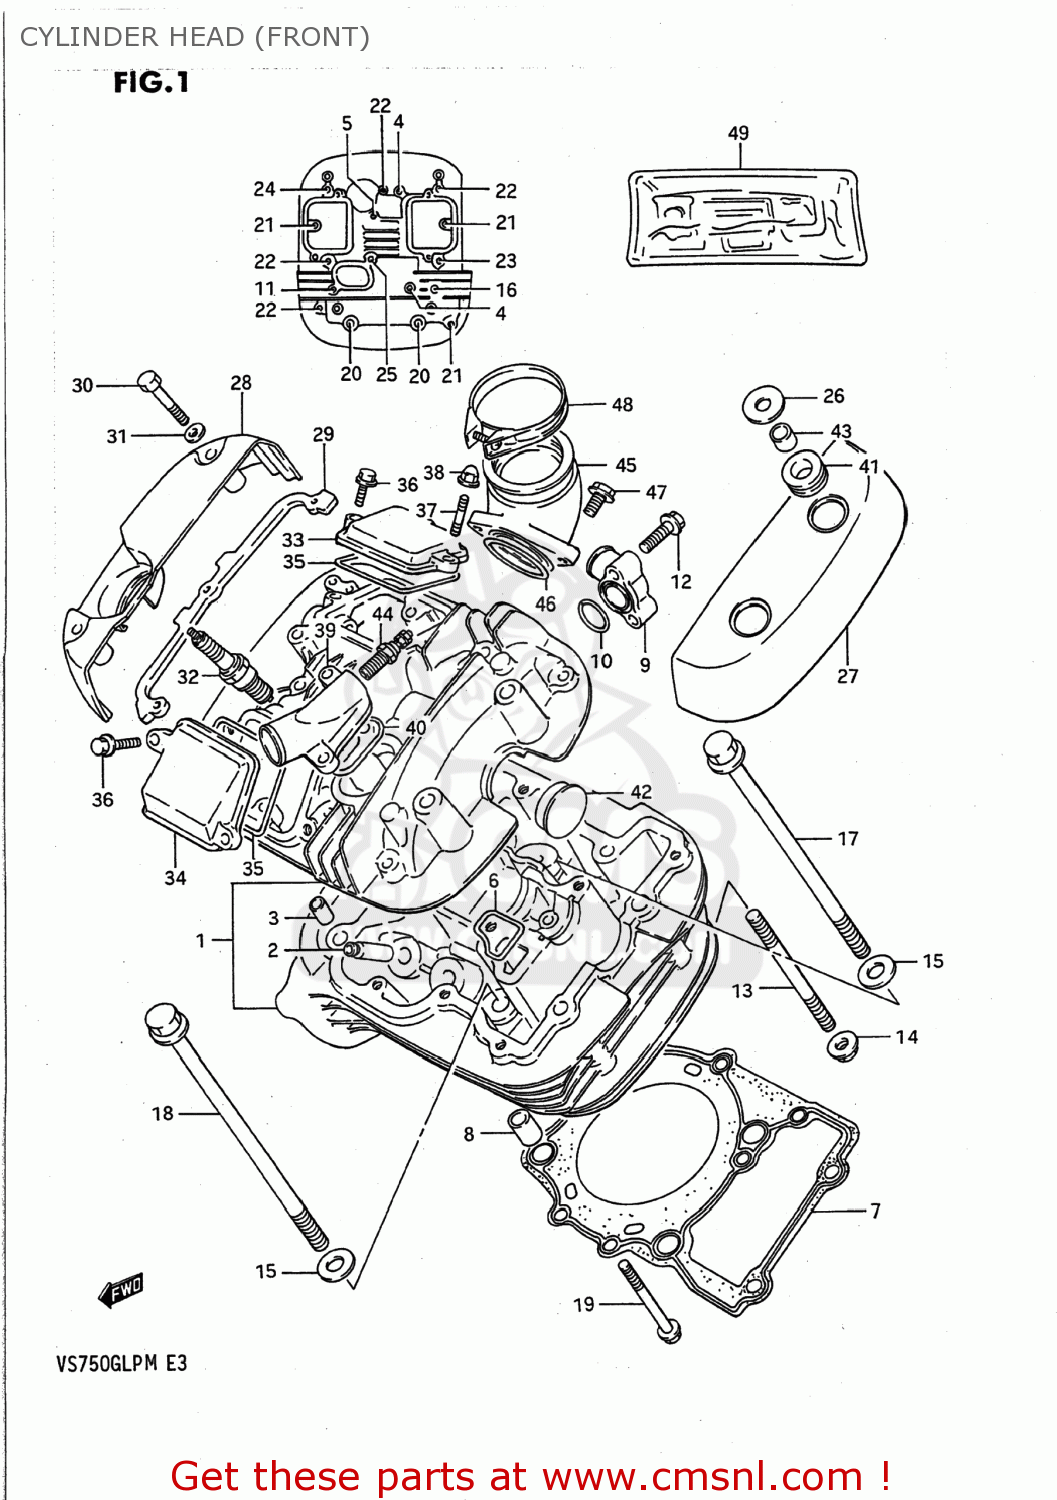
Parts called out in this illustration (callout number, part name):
1	HEAD ASSEMBLY,CYLINDER,FRONT
2	GUIDE,VALVE
3	PIN(11X14)
4	BOLT(6X50)
5	BOLT(6X55)
6	GASKET,CYLINDER HEAD WATER (NAS)
7	GASKET,CYLINDER HEAD FR (MCA)
8	PIN
9	UNION,CYLINDER HEAD WATER
10	O RING(D:2.4,ID:17.8)
11	BOLT 6X20
12	BOLT
13	BOLT,STUD
14	NUT
15	WASHER(10.5X22X2.3)
16	BOLT(8X140)
17	BOLT(10X155)
18	BOLT(10X165)
19	BOLT
20	BOLT(8X245)
21	BOLT 6X25
22	BOLT
23	BOLT
24	BOLT
25	BOLT(6X55)
26	WASHER (8.2X24X1.6)
27	CAP,CYLINDER HEAD COVER FR,L
28	CAP,CYLINDER HEAD COVER FR,R
29	CUSHION,FR,R CAP
30	BOLT
31	WASHER
32	PLUG,SPARK(DPR8EA-9)
33	CAP,INSPECTION
34	CAP,INSPECTION,EXHAUST
35	GASKET,INSPECTION CAP (NAS)
36	BOLT
37	STUD 6X16
38	NUT
39	UNION
40	GASKET,WATER OUTLET UNION (NAS)
41	CUSHION
42	PLUG
43	BUSH
44	GAUGE ASSY,WATER TEMP
45	PIPE,INTAKE
46	O-RING (D:2.4 ID:39.7)
47	BOLT
48	CLAMP,PIPE
49	GASKET SET (MCA)
